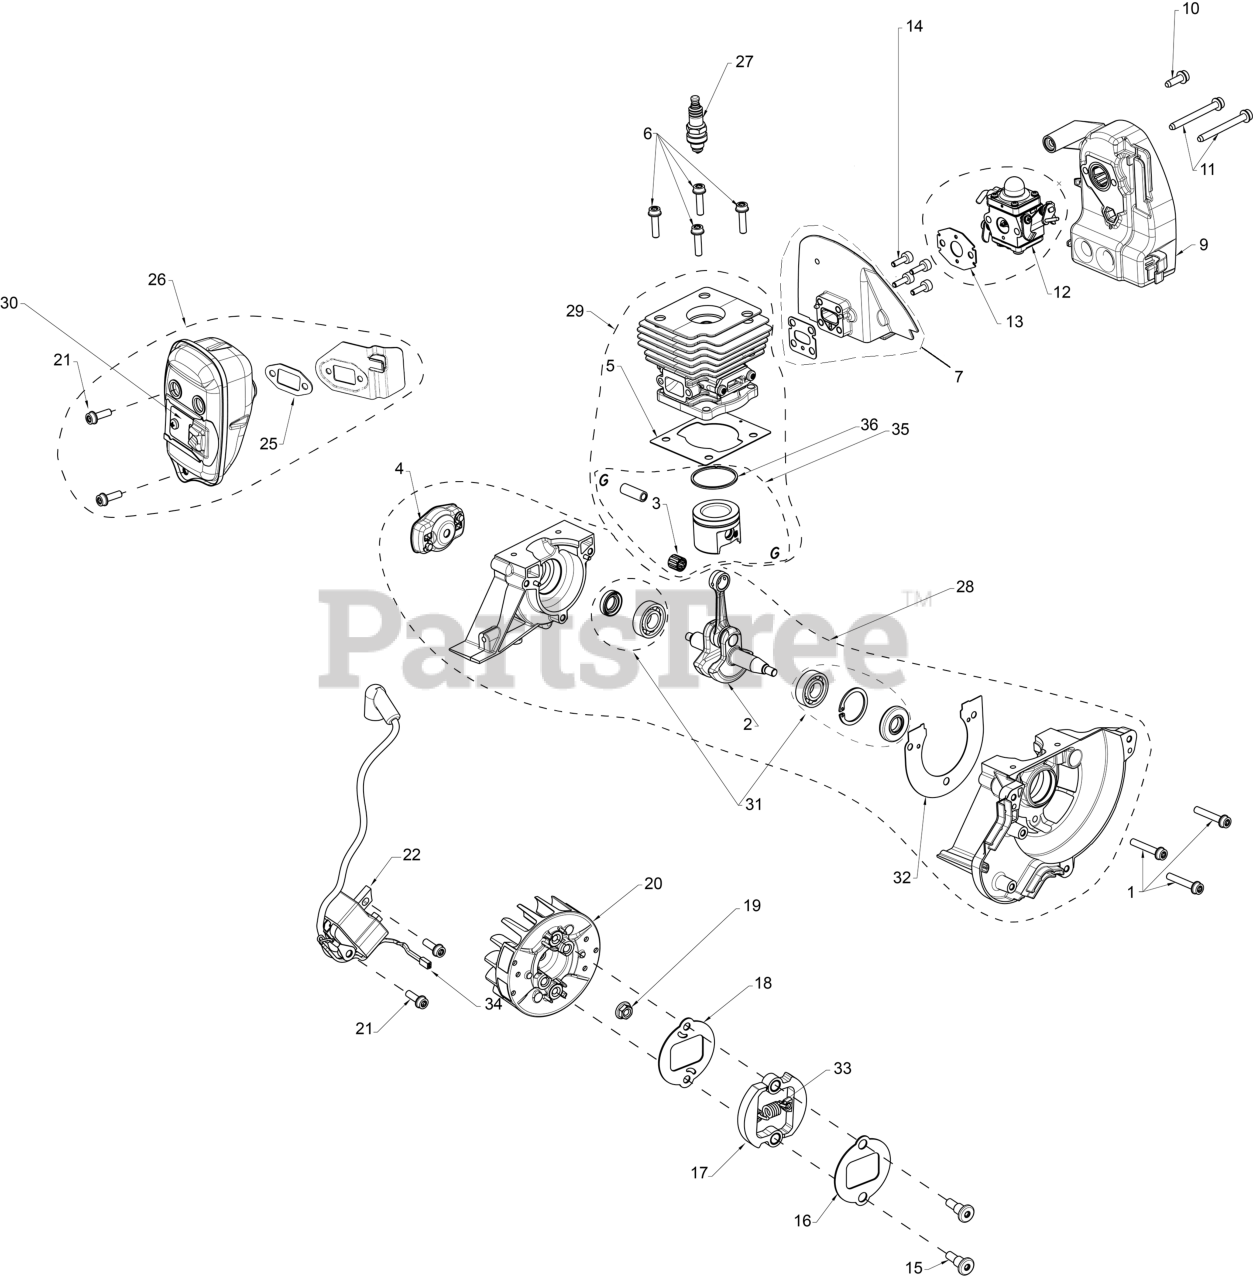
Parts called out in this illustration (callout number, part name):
1	SCREW
2	CRANKSHAFT ASSY
3	Bearings
4	STARTER PAWL BRIDGE
5	GASKET CYLINDER BASE
6	SCREW
7	GASKET
7	Insulation Wall
9	ASSY FILTER HOLDER
10	SCREW
11	SCREW
12	KIT CARBURETOR
13	GASKET CARB ADAPTER
14	SCREW ITXSCM
15	SCREW CLUTCH
16	WASHER CLUTCH UPPER
17	CLUTCH ASSY
18	WASHER CLUTCH LOWER
19	FLANGE NUT
20	FLYWHEEL
21	SCREW
22	Ignition Module
25	GASKET
26	MUFFLER KIT
27	KIT SPARK PLUG
28	KIT CRANKCASE ASSY
29	KIT PISTON/CYLINDER
30	KIT SPARK ARRESTOR
31	SEAL KIT AND BEARING
32	GASKET CRANKCASE
33	SPRING CLUTCH
34	CABLE SHORT CIRCUIT ENGINE
35	KIT PISTON 129
36	PISTON RING 36MM
